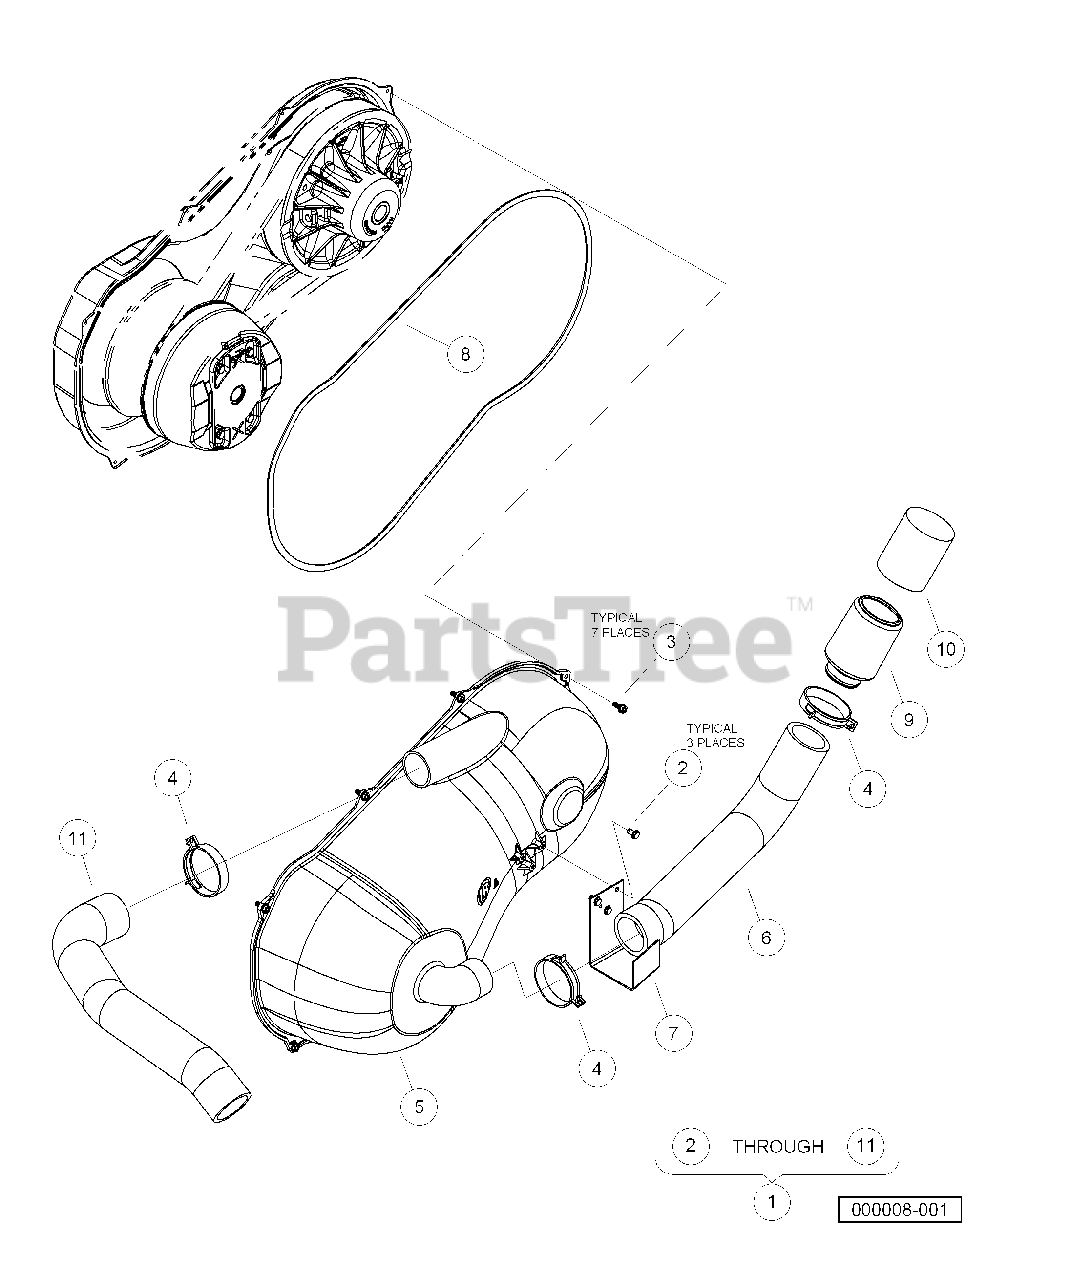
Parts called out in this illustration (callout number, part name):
1	Kit, Sealed CVT Cover
2	Screw, 1/4-15 X 1.50 Hi-lo Hex
3	Screw, M6 X 16 Tt Hx Fl Hd
4	Clamp, Hose, Ctb 64mm
5	Cover, CVT Outer
6	Hose, Inlet, Cover, CVT
7	Bracket, Inlet, Cover, CVT
8	Gasket, Cover, CVT
9	Cap, Inlet, Cover, CVT
10	Filter, Inlet, Cover, CVT
11	Hose, Outlet, Cvt
